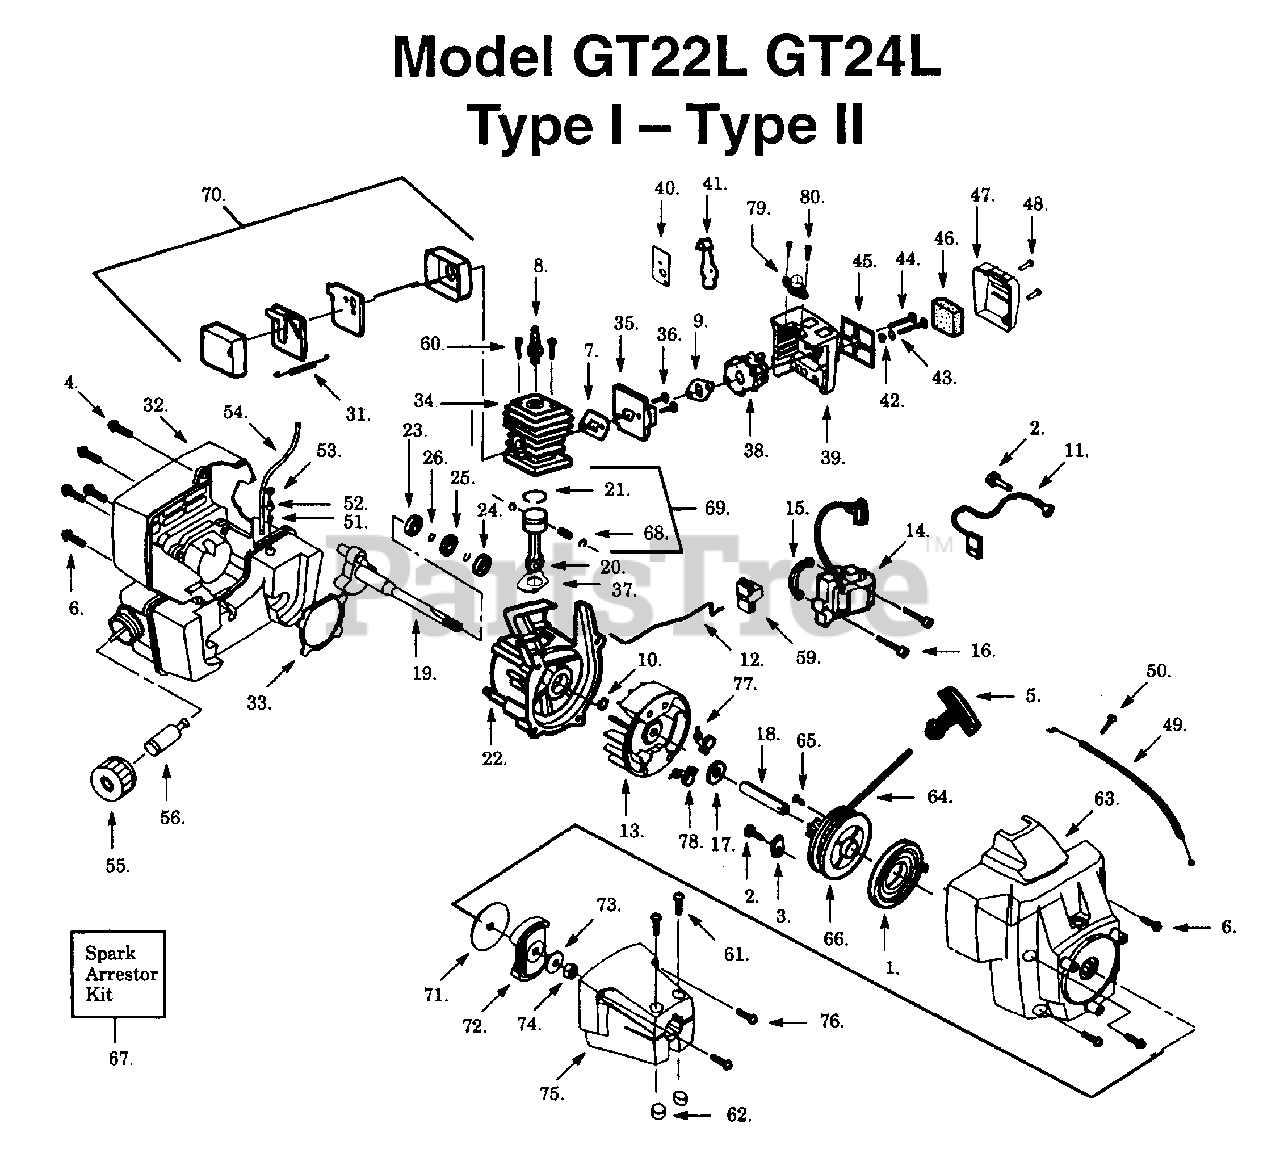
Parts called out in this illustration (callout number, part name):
1	SPRING-STARTER
2	SCREW 8-16 X 9/16 (PLAS
5	HANDLE-STARTER
6	SCREW - SHROUD
7	GASKET
8	SPARK PLUG CJ8 NLA
9	GASKET
10	RETAINING RING
11	LEADWIRE SWITCH
13	FLYWHEEL
14	IGNITION MODULE
15	SPACER - IGNITION MODULE
17	WASHER FLAT
19	CRANKSHAFT ASSEMBLY
20	CONNECTING ROD
21	PISTON RING
22	CRANKCASE ASSY
23	BEARING
25	SEALING RING
31	MUFFLER SPRING
33	GASKET, CRANKCASE
36	SCREW - CARB. ADAPTOR
37	REPL BY 530 01 92-23
40	CHOKE PLATE
41	CHOKE FLAP
43	CHOKE SPACER
45	FILTER PLATE
46	AIR FILTER FOAM
47	AIR FILTER COVER
48	SCREW - THROTTLE HOUSING
51	VALVE-CHECK (DUCKBILL)
55	REPL BY 530 01 43-47
56	FUEL PICK UP ASSY
61	SCREW-10-24 X 1-3/8 (UN
62	LOCKNUT-HEX 10-24
63	REPL BY 530 04 74-93
65	SCREW-6-19X9/32 PAN/SEM
66	STARTER PULLEY KIT
67	KIT-SPARK ARRESTOR (OLD STYLE)
68	WRIST PIN RET.
69	PISTON
71	FRICTION DISC,CLUTCH 36/41
72	CLUTCH ASSEMBLY KIT
73	WASHER-FLYWHEEL
76	SCREW-10-14 X 13/16 (PL
78	SPRING
79	PRIMER BULB ASSEMBLY
5300353-29	CARBURETOR
5300353-50	CARBURETOR
5300374-87	TANK
